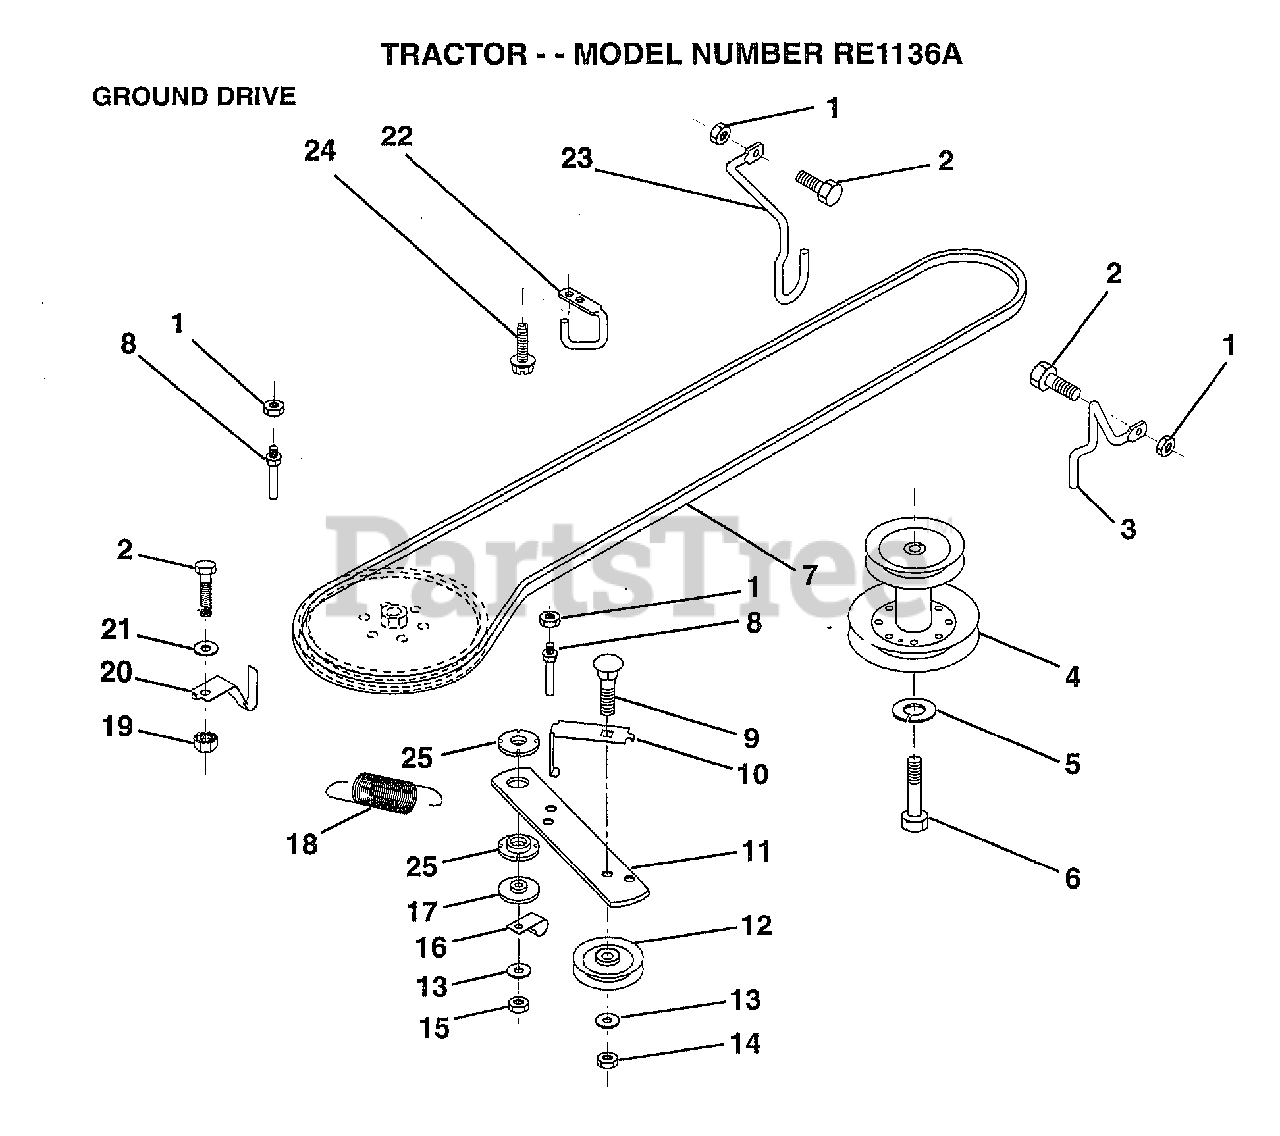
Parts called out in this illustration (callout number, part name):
2	BOLT
3	KEEPER RH
4	PULLEY.ENGINE.LR
5	LOCKWASHER
6	HEX BOLT
7	V BELT
8	"KEEPER,DRIVE BELT"
9	BOLT
10	"KEEP,IDLER DR BEL"
11	ARM-IDLER.DR.GRND
12	PULLEY.IDLER.FLAT
13	WASHER
14	LOCKNUT
16	"CLIP,INSULATOR"
17	SPACER
20	KEEPER.BELT.T/A
21	WASHER
22	"KEEPER,FRA DR BEL"
23	KEEPER MOWER LH
24	SCREW
25	BUSHING.NYLON
